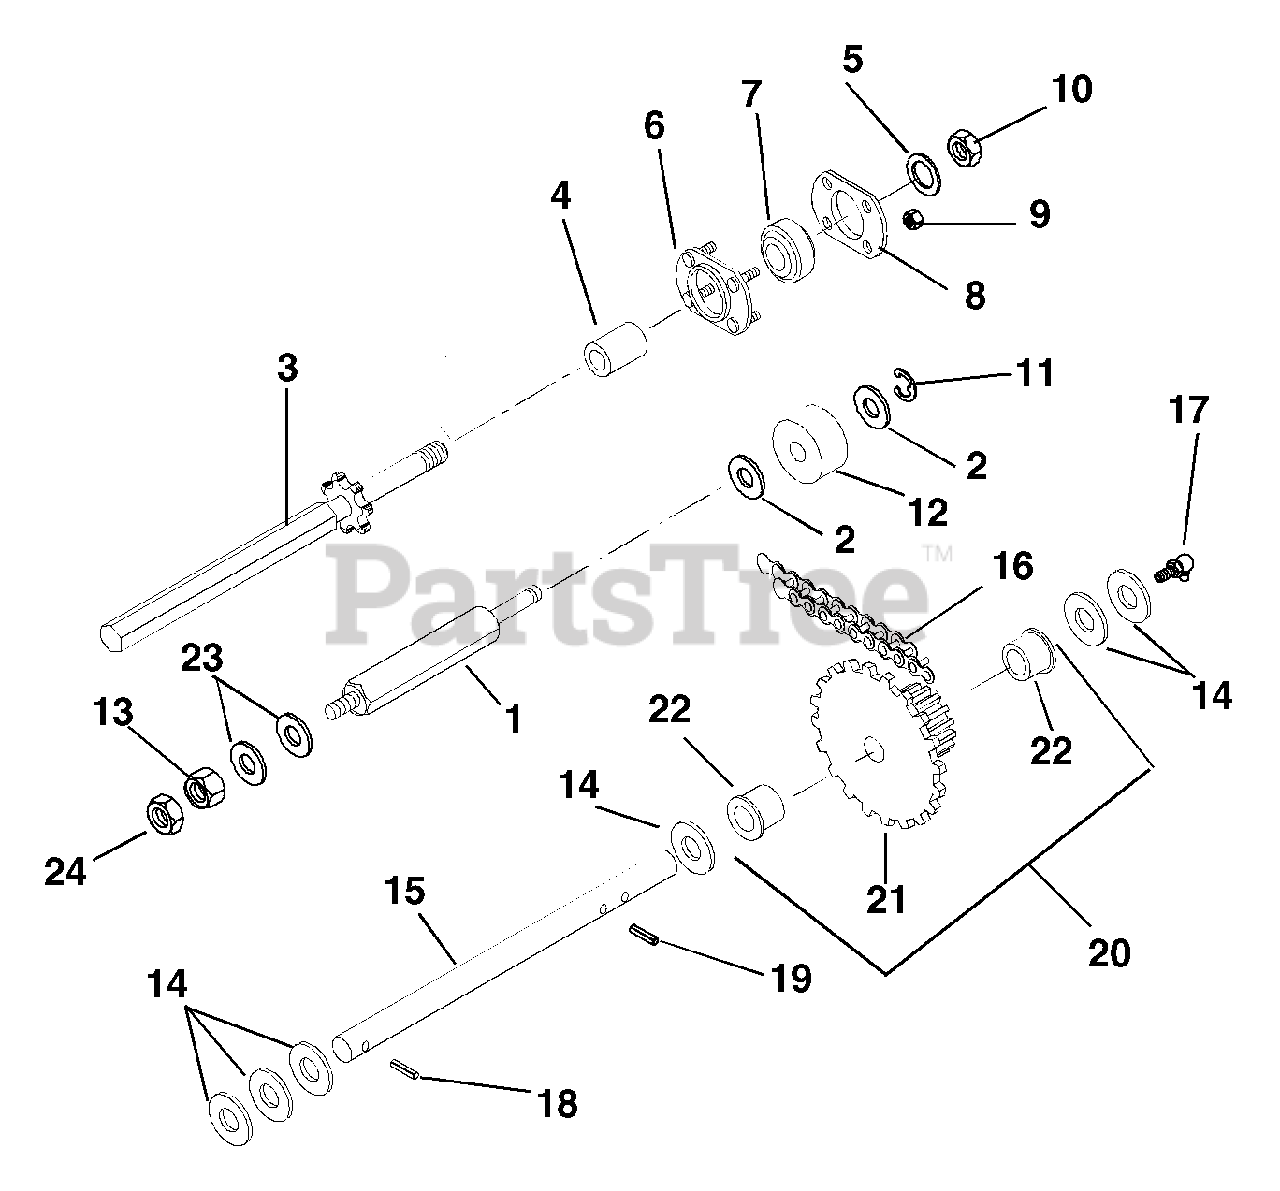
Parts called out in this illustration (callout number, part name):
1	SHAFT, HEX
2	@WSHR-FL-STL.344X.688X.065YWZC
3	SHAFT, HEX - W/SPROCKET
4	BSHG-SLV .450X.750X1.600
5	WSHR-FL-STL .505X.880X.072 YWZ
6	BEARING FLANGE
7	BRG-BALL .437X1.375X.437
8	BEARING FLANGE
9	NUT-LK-DUAL FACE 10-24 YWZC
10	@NUT-LK-CTR .44-14 YWZC
11	RG-RTNG-EXT. .31X.025
12	IDLER 1.38 OD X .31 ID X .69
13	@NUT-LK-CTR .31-18 YWZC
14	WSHR-FL-STL .630X1.005X.062 YZ
15	PINION SHAFT
16	ROLLER CHAIN #41 - 34 PITCHES
17	DRIVE FITTING, HYD. BRIGHT ZC
18	PIN-ROLL .156X1.00
19	PIN-ROLL .125X1.00
20	PINION & SPROCKET ASSEMBLY
21	PINION & SPROCKET
22	BSHG-FLG .625X.750X.500X.875BR
23	@WSHR-FL-STL.38X.875X.083 YWZC
24	NUT- JAM .312-18 YWZC
